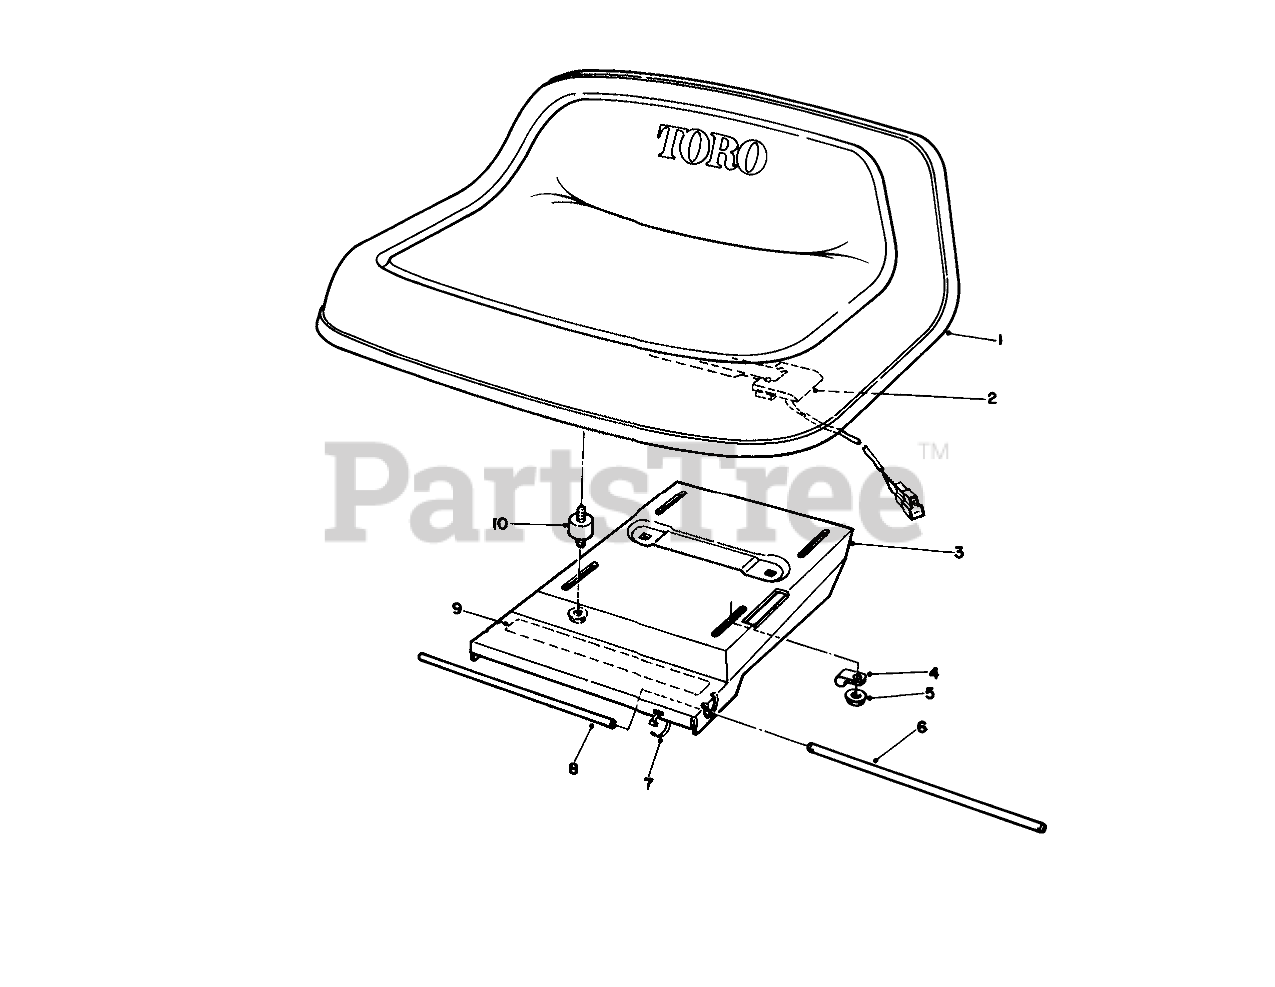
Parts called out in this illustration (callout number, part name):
2	SWITCH-SEAT
3	Base-Seat
4	CLAMP
5	NUT-HF
6	SEAT BASE ROD
7	TIE-CABLE
8	TUBE-SEAT
9	DECAL
10	ISOLATER-SEAT
